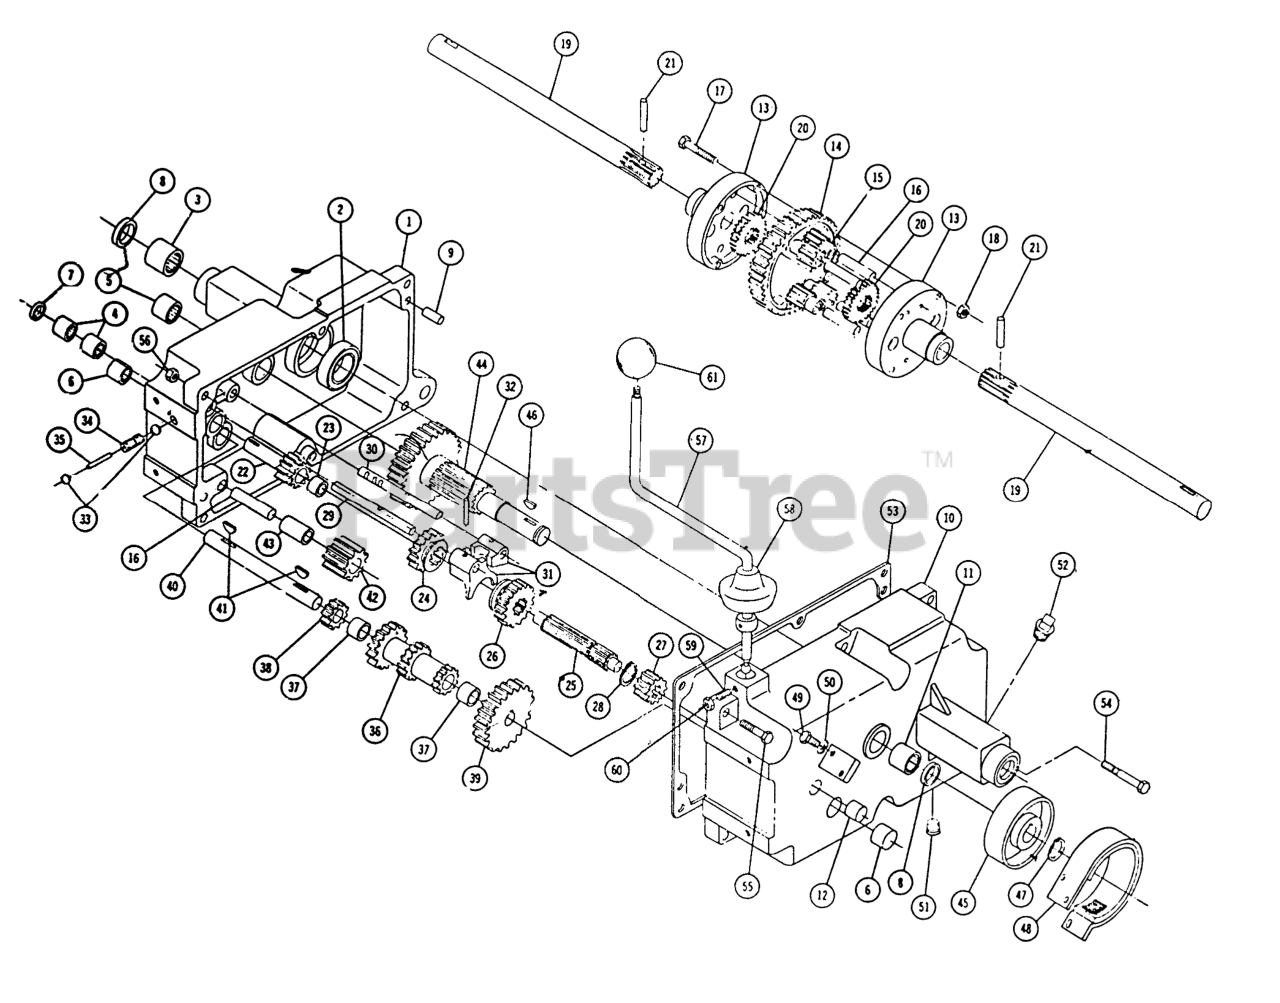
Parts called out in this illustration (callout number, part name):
3	BEARING-NEEDLE
5	BEARING-NEEDLE
6	BEARING-NEEDLE
9	PIN-DOWEL
13	DIFFERENTIAL CASE
14	SVC BULLT 394
16	PIN-DIFFERENTIAL
20	AXLE GEAR
23	BEARING-NEEDLE
27	GEAR
29	RAIL-SHIFT
30	RAIL-REAR SHIFT
31	FORK-SHIFT
32	PIN-ROLL
33	BALL-DETENT
35	PIN-SHIFT
37	BUSHING-BRONZE
39	GEAR-CLUSTER SHAFT
41	Key
42	GEAR/BUSHING ASM-REVERSE IDLER
43	BUSHING
46	KEY-WOODRUFF
48	BRAKE BAND & LINER A
49	Bolt-1/4-20 x 5/8
50	Lockwasher
53	GASKET-TRANSMISSION
54	Bolt Hex 3/8-16 x 1
55	Bolt, 3/8 16 x 2
58	COVER-DUST
59	SETSCREW
60	Nut-Nylok
